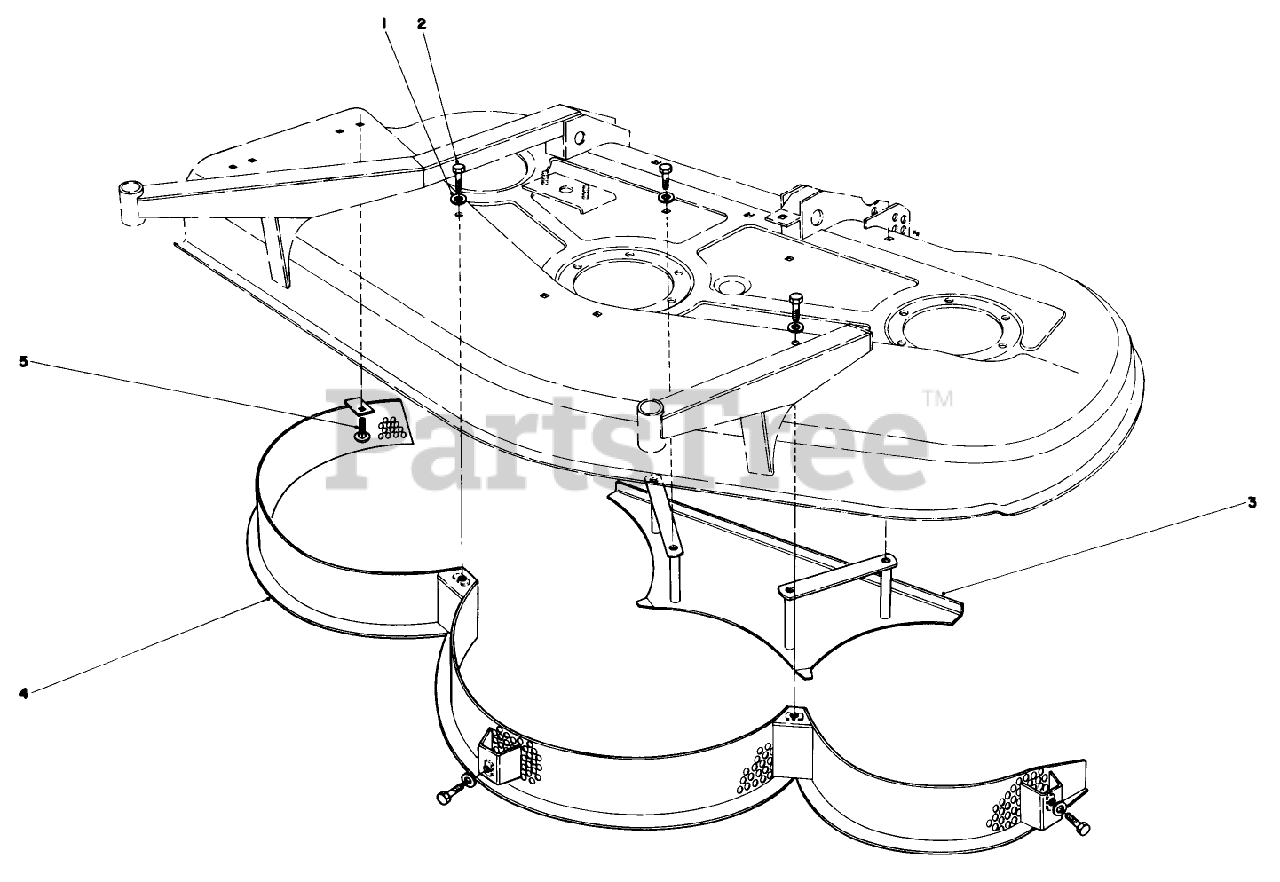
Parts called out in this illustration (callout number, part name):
1	WASHER-LOCK
2	SCREW-HH
3	Shelf Bottom Rear
4	Mulcher Screen
5	BOLT-CARR
